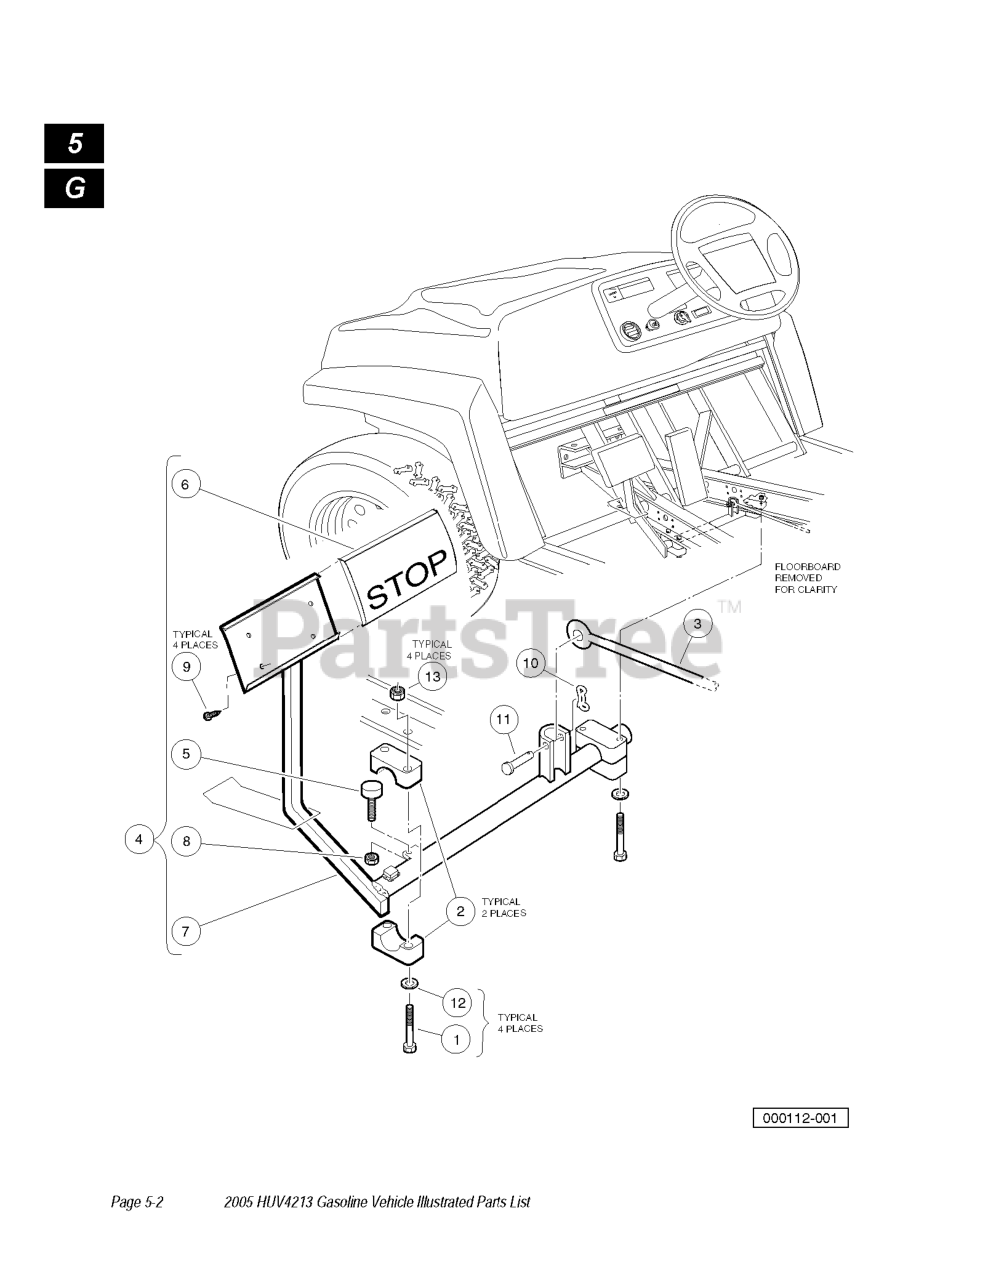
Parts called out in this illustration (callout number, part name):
1	SCREW HEX CAP
2	PACKAGE, BRAKE MOUNTING BLOCK
3	EQUALIZER ROD
4	BRAKE PEDAL ASM HYD
5	BUMPER, BRAKE PEDAL RUBBER
6	PAD, HYDRAULIC BRAKE PEDAL
7	Brake Pedal Weld Asm
8	NUT, 1/4-20 HEX
9	SCREW TYPE AB SHT MTL
10	PIN, BOW TIE LOCKING - .072
11	PIN, 3/8 X 1-5/16 CLEVIS
12	WASHER, 5/16 TYPE A FLAT
13	LOCKNUT, 5/16-18 NYLON INSERT
